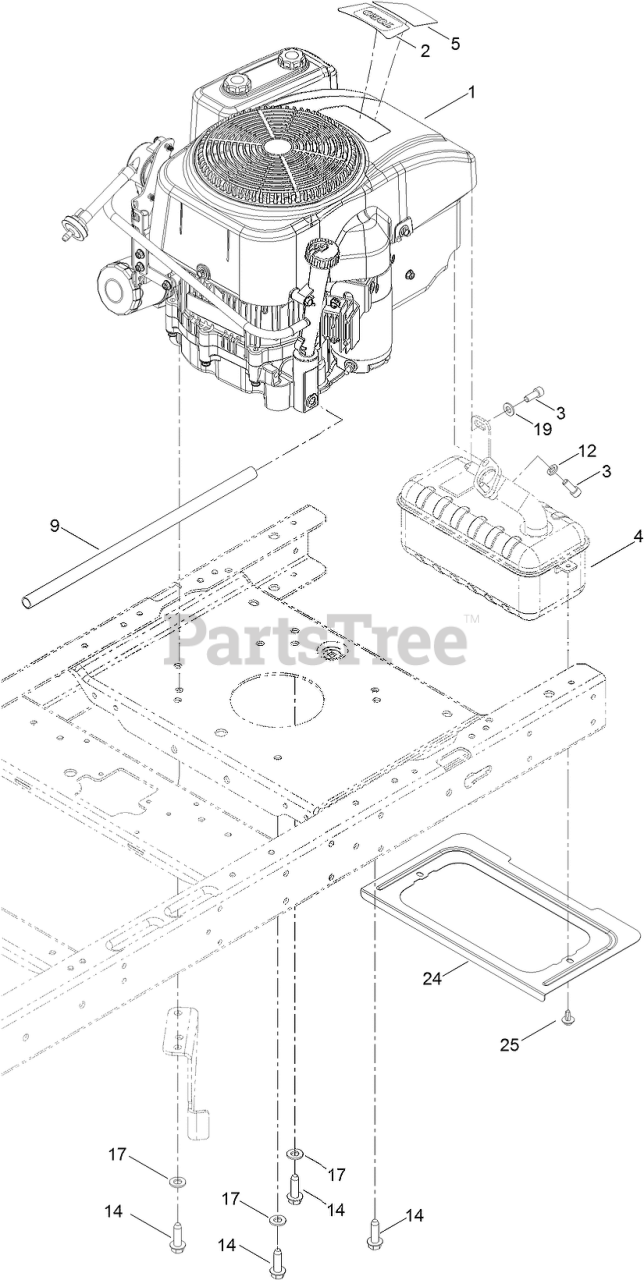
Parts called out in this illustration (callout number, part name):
1	ENGINE-1P92F-1
2	DECAL-ENGINE
3	SCREW-HSH
4	MUFFLER
5	DECAL-DISPLACEMENT, ENGINE
9	TUBE-DRAIN, OIL
12	WASHER-LOCK
14	SCREW-TAPTITE
17	WASHER-FLAT
19	WASHER-PLAIN
24	SHIELD-HEAT
25	SCREW-HHFTF
